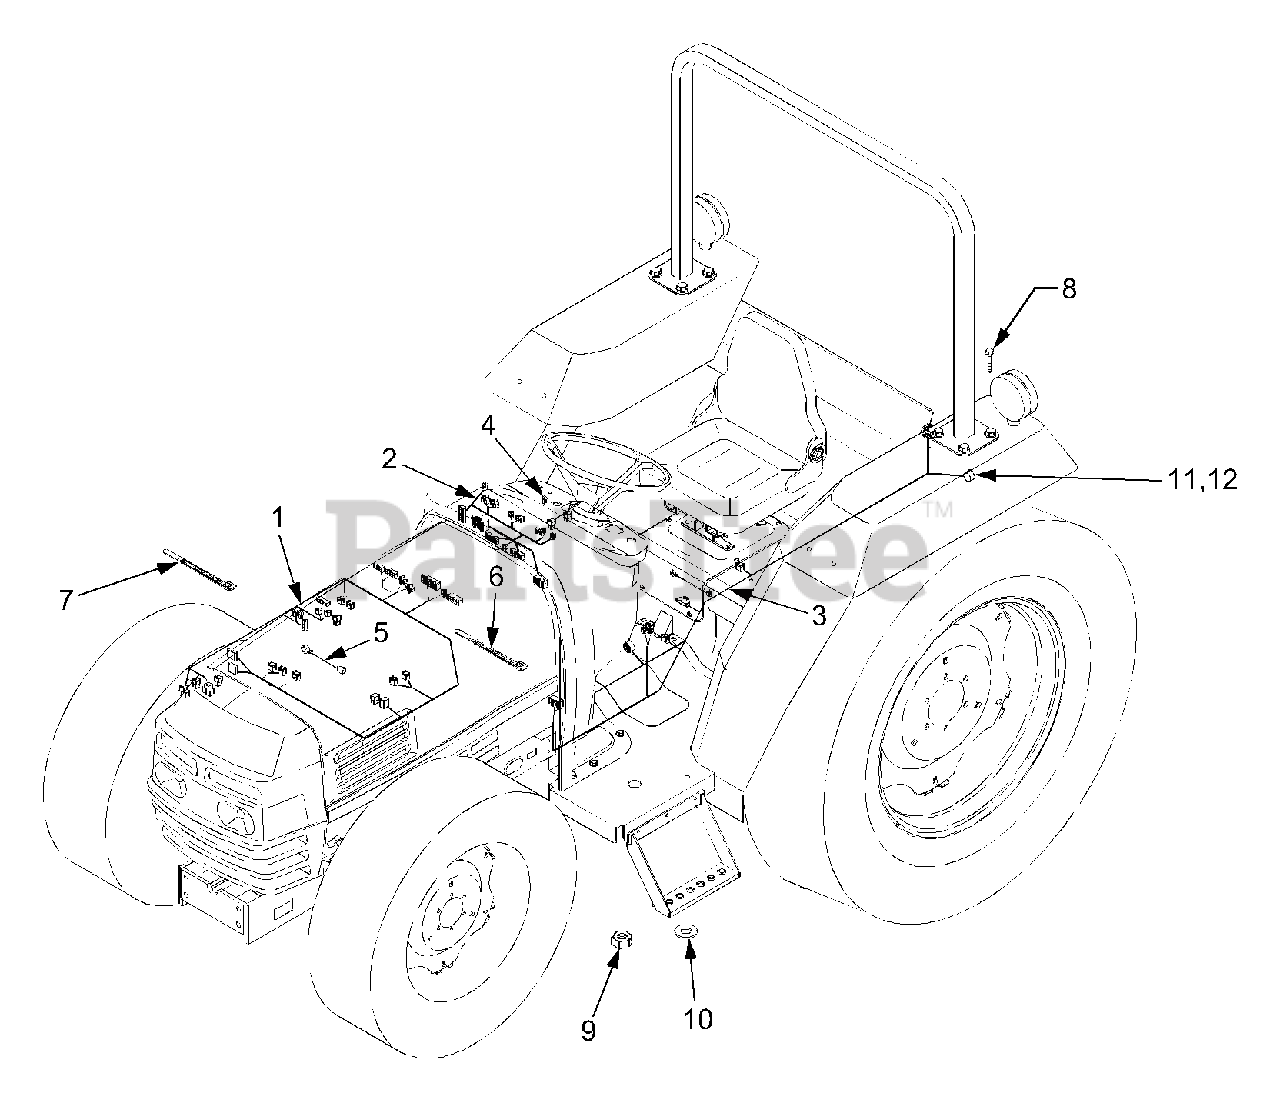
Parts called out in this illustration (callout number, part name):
1	Bonnet Wire Harness Ass'y
2	Panel Wire Harness Ass'y
3	Fender Wire Harness Ass'y
4	Wire Harness 2
5	Wire Harness 3
10	Washer, Spring
11	Wire, Connection(LH)
12	Wire, Connection(RH)
